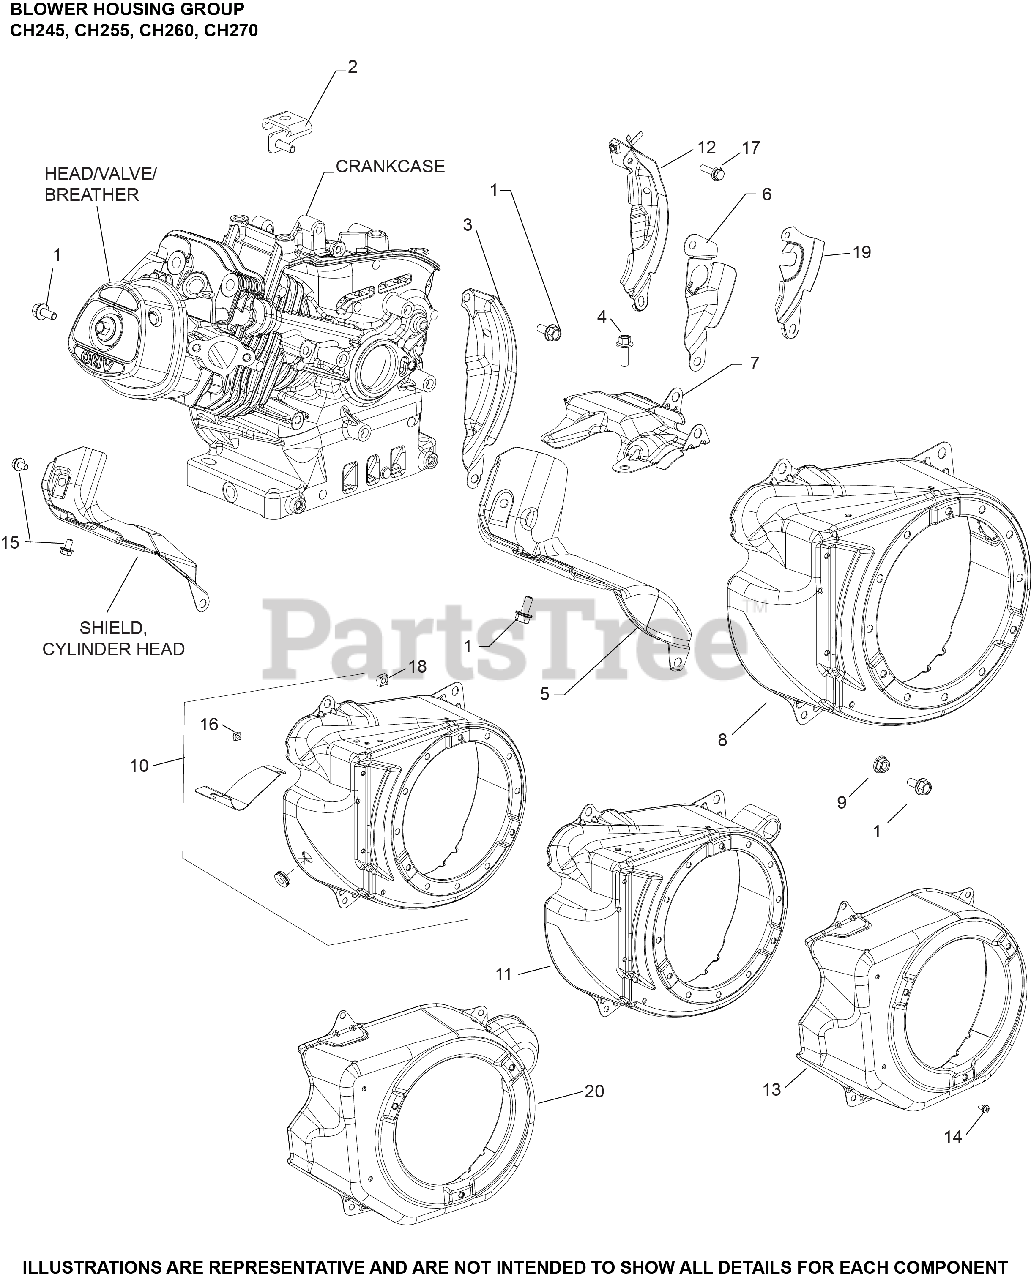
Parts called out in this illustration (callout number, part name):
1	SCREW, HEX FLANGE (M6)-USE 25 086 433-S
3	SHIELD, FLYWHEEL
4	SCREW, M6 X18
5	SHIELD, CYLINDER HEAD
7	SHIELD, UPPER HEAT
8	HOUSING, BLOWER ASSEMBLY
9	NUT, HEX FLANGE (M6) - USE 14 100 16-S
16	NUT, BLOWER HOUSING (CKY)
18	NUT, BLOWER HOUSING (CKY)
